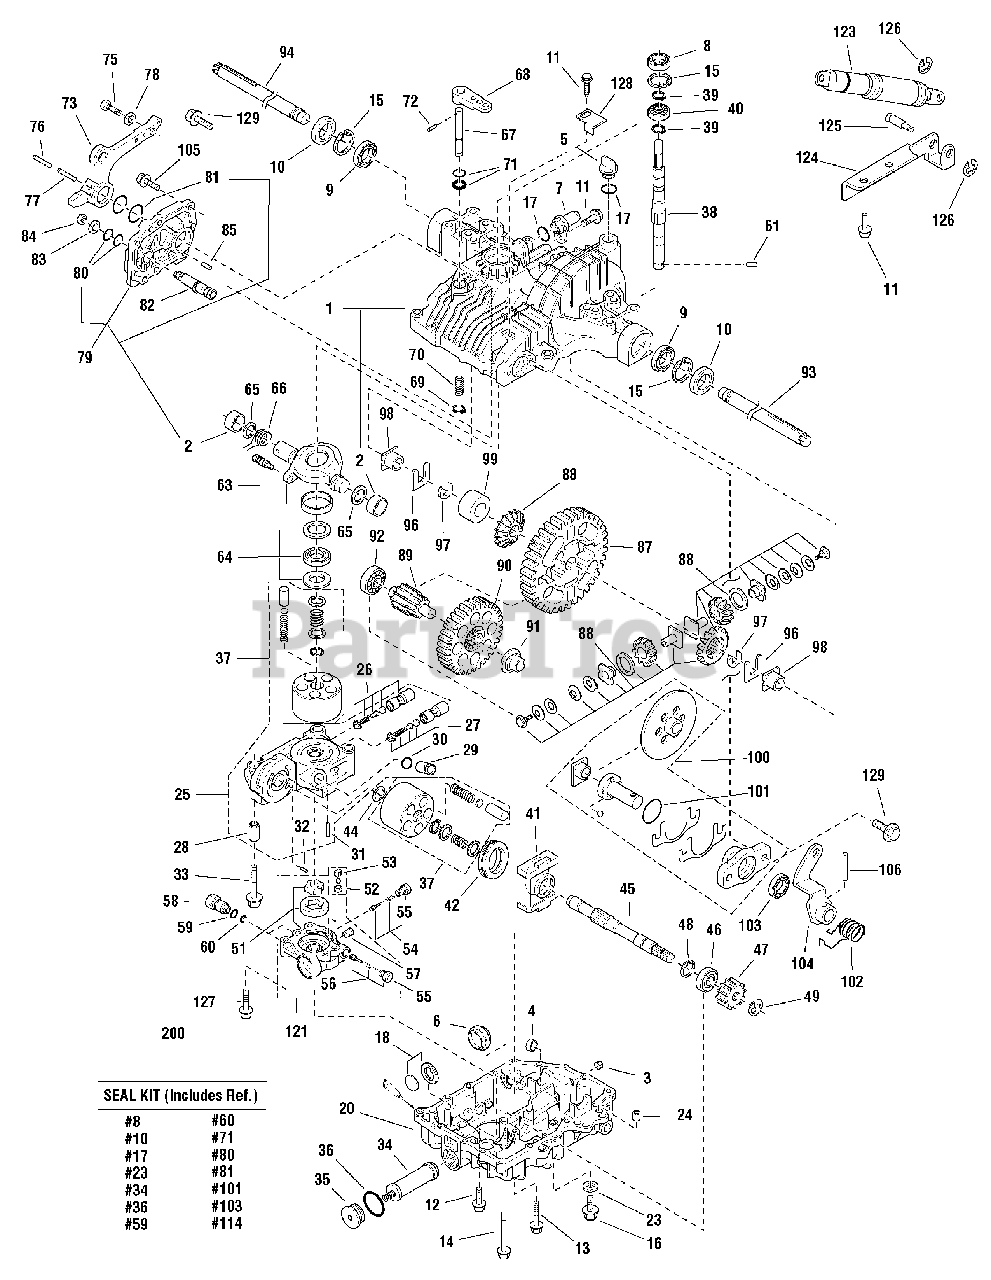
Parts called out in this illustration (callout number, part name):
1	*UPPER HOUSING, Complete
2	BEARING, 28 x 15
3	TAPER PLUG, 1/8
4	BORE PLUG, 17
5	CAP, Oil, 20
10	SEAL
11	SCREW, Tapping, 8 x 25
12	SCREW, Tapping, 8 x 30
14	BOLT, 8 x 75
16	BOLT, 10 x 12
17	PACKING, P18
18	MAGNET, Complete
20	LOWER HOUSING, Complete
23	WASHER, Seal 10
24	PIPE, 13 x 11.3
25	*CENTER CASE, Complete
26	*VALVE, (A-1 SET)
27	*VALVE, (A-2 SET)
28	KNOCK PIN, 15.5 x 30
29	PLUG, 16 x 25
32	PIN, 3 x 9.8
33	BOLT, 10 x 75
34	FILTER
37	*CYLINDER BLOCK, Complete
40	BEARING, 6303
41	*HOUSING
44	WASHER, 18 x 31 x 1
45	*SHAFT MOTOR
46	BEARING 6004 SH2 U
47	*MOTOR GEAR
49	RING, E15
51	*PUMP CASE, Complete
52	*3RD CHECK, Complete
53	*HOLDER, (Seat)
54	*VALVE, (Imp Complete)
55	*PLUG
56	*VALVE, (Charge Complete)
57	PLUG, PT 1/8
60	PACKING, 6.1
61	PIN, 3.2 x 21
63	*SWASH PLATE, Complete
64	*BEARING, Complete
65	*WASHER
66	*SPRING (N/C)
67	*SHAFT (BYPASS)
68	*LEVER (BYPASS)
71	O-RING, 1A P10A
72	PIN, 3.0A*20
73	CONTROL LEVER
76	PIN, 6.0A x 50
77	PIN, 3.5A x 50
79	*SIDE COVER SET
80	PACKING, P14
81	PACKING, P28
82	*FULCRUM, (ECCENT)
87	*FINAL GEAR
88	DIFFERENTIAL GEAR KIT
89	*SHAFT, (F PINION)
90	*REDUCTION GEAR
93	*AXLE SHAFT, Left
94	*AXLE SHAFT, Right
96	THRUST WASHER
98	*BUSHING
99	*COLLAR, (Diff. Lock)
102	SP, (RETURN)
103	SEAL, TC173007
104	*ARM, (BRAKE)
106	PIN, 6.0A x 4.0
121	PUMP CASE S/A
123	SHOCK ABSORBER
127	BOLT, 8 x 45
128	STOPPER, Brake
129	BOLT, 8 x 25
200	SEAL KIT, K71H, E, J, L
